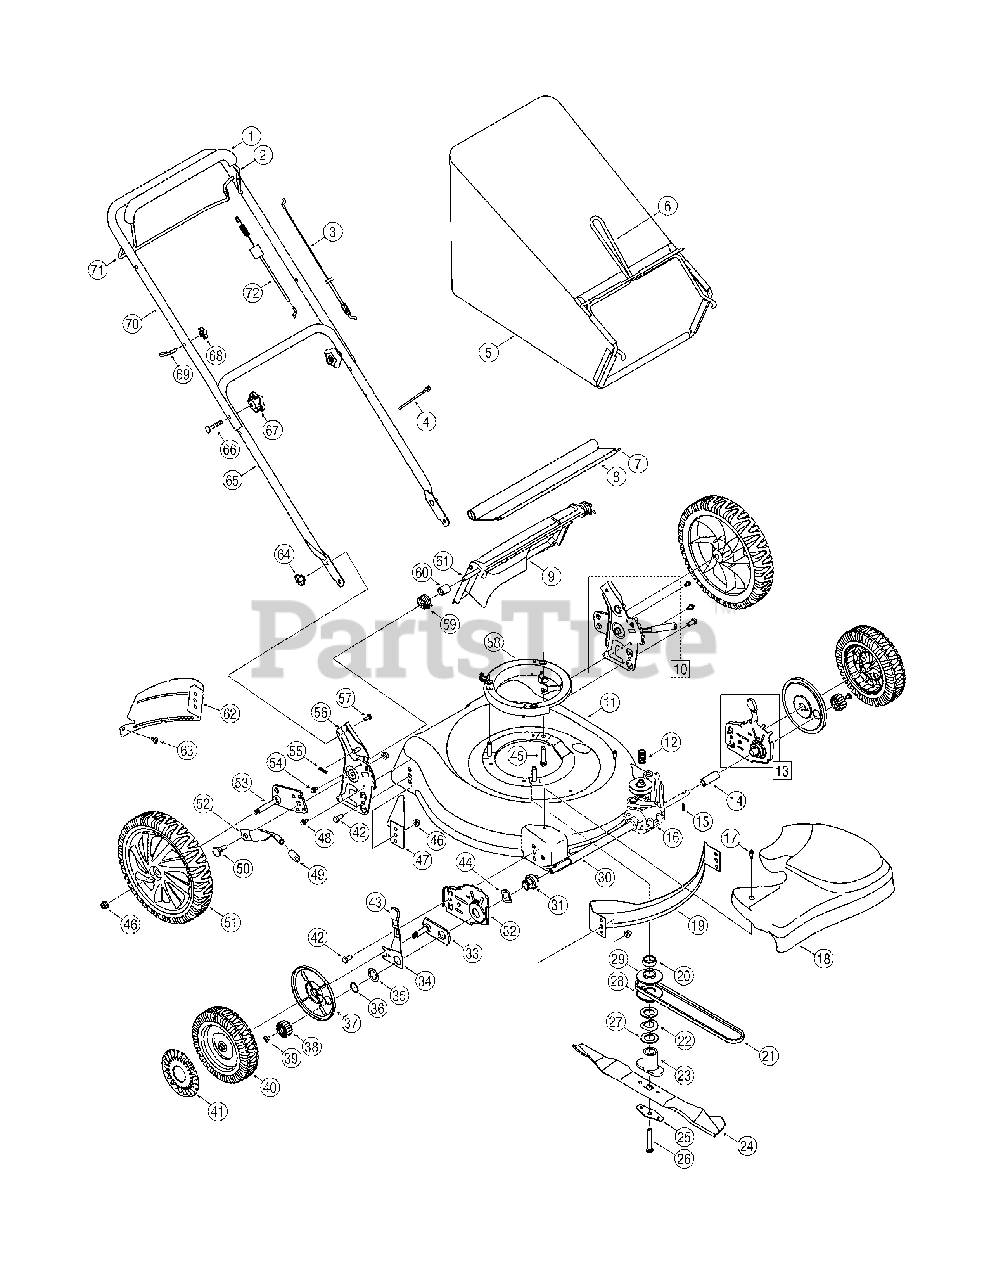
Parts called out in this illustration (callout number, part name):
1	Bail Cover
2	Blade Control
3	Control Cable 37.75-inch
4	Cable Tie
5	Grass Bag Assembly
7	Trailshield Wire
8	Trailshield
9	Rear Door
10	Height Adj. Bracket Assy
11	21-inch Deck
12	Compression Spring
13	Front Height Adj. Assy - LH
13	Front Height Adj. Assy - RH
14	Sleeve Spacer .52 ID x 1.5
15	Dowel Pin
16	Transmission
17	Shoulder Screw
18	Deck Cover
19	Front Baffle
20	Sleeve Spacer
21	V-Type Belt
22	Spring Washer 1.005 x 1.825
23	Blade Adapter with Star
24	21-inch Mulching Blade
25	Bell Blade Spacer
26	Screw 3/8-24 x 2.5
27	Flat Washer 1 x 1.75
28	Key Half Pulley
29	Upper Half Pulley
30	Sleeve Spacer
31	Front Bearing Assembly
32	Adjustment Plate RH
32	Adjustment Plate LH
33	Pivot Plate Assembly
34	Spring Lever RH
34	Spring Lever LH
35	Flat Washer 1.01 x 1.5 x .
36	Snap Ring
37	Wheel Cover
38	Spur Gear 14T RH
38	Spur Gear 14T LH
39	Screw 1/4-20 x .39
40	Front Wheel 8 x 2.125 Gear
41	Hubcap
42	Screw 3/8-16 x .75
43	Knob
44	Wave Washer 1.5 x 1 x .
45	Screw TT 3/8-16 x 1.875
46	Flange Lock Nut 3/8-16
47	Rear RH Baffle
48	Screw TT 1/4-20 x .625
49	Foam Grip
50	Shoulder Screw
51	Rear Wheel 12 x 2.125 Idle
52	Spring Lever
53	Pivot Arm Assembly RH
53	Pivot Arm Assembly LH
54	Screw TT 1/4-20 x .5
55	Hairpin Clip
56	Handle Bracket Assembly RH
56	Handle Bracket Assembly LH
57	Screw 1/4-20 x .75
58	Engine Spacer
59	Torsion Spring RH
59	Torsion Spring LH
60	Spacer
61	Pivot Rod
62	Rear Baffle LH
63	Screw AB 1/4-14 x .625
64	Wing Nut
65	Lower Handle
66	Carriage Bolt 5/16-18 x 2
67	Star Knob
68	Handle Knob
69	Eye Bolt
71	Drive Control
72	Control Cable 51-inch
